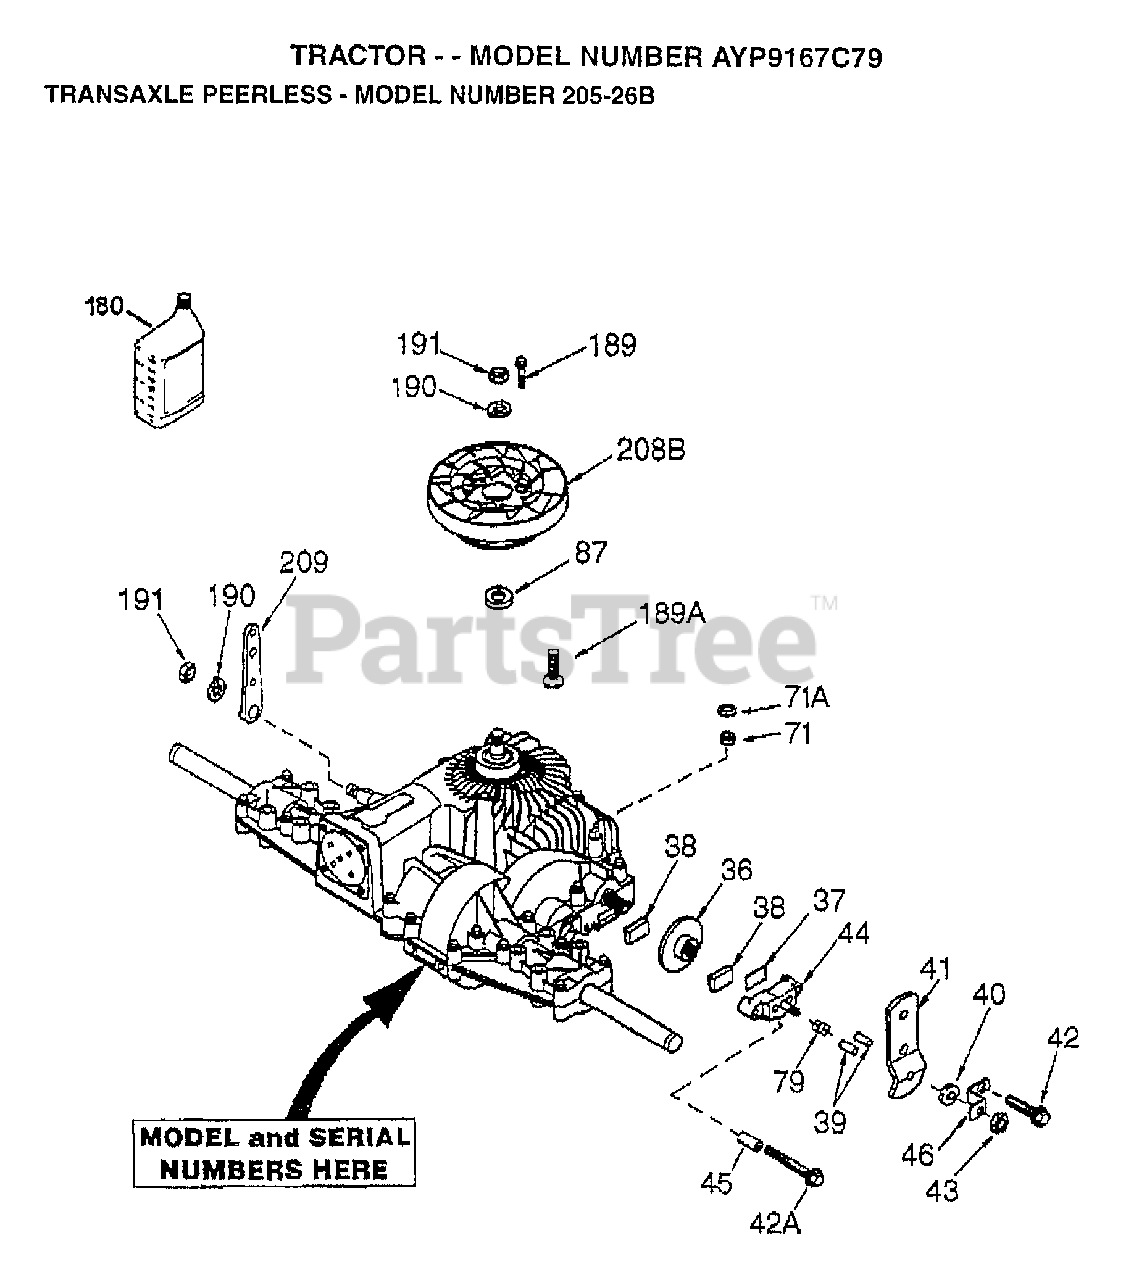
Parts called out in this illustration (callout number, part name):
37	PLATE BRAKE PAD
41	BRAKE LEVER
42	SCREW, 1/4-20 X 1-1/4
42A	SCREW, 1/4-20 X 2-1/4
43	LOCKNUT 5/16-24
44	HOLDER BRAKE PAD
46	BRAKE LEVER BRACKET
71	SEAL SQUARE CUT
180	GEAR OIL 80W90
189	DRIVE SCREW
208B	FAN/COUPLING
209	CONTROL LEVER
